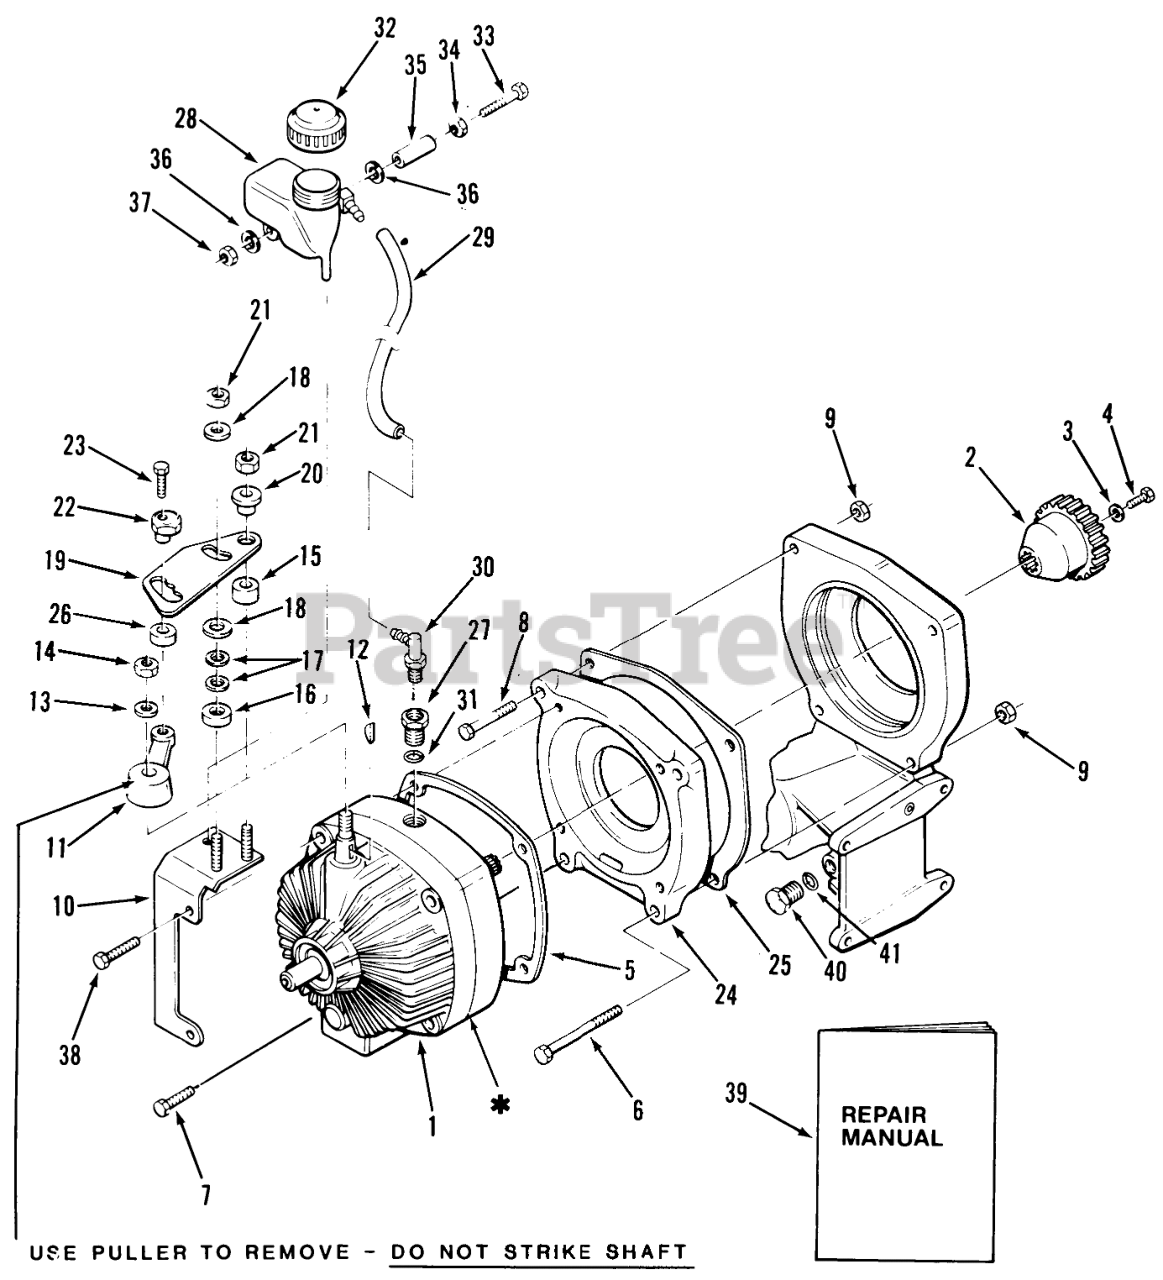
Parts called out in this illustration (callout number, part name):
2	GEAR 20TEETH DRIVE
3	WASHER
10	CONTROL SUPPORT ASSY *R
12	KEY WOODR 1/8X1/2 DI
15	SPACER-PIVOT
16	SPACER-FRICTION
17	WASHER-SPRING DISC
18	FRICTION WASHER
19	CAM-SPEED CONTROL (NS)
20	CAM-SPACER
21	NUT-HEX
25	GASKET
35	SPACER
39	Repair Manual
40	PLUG-WITH O-RING
